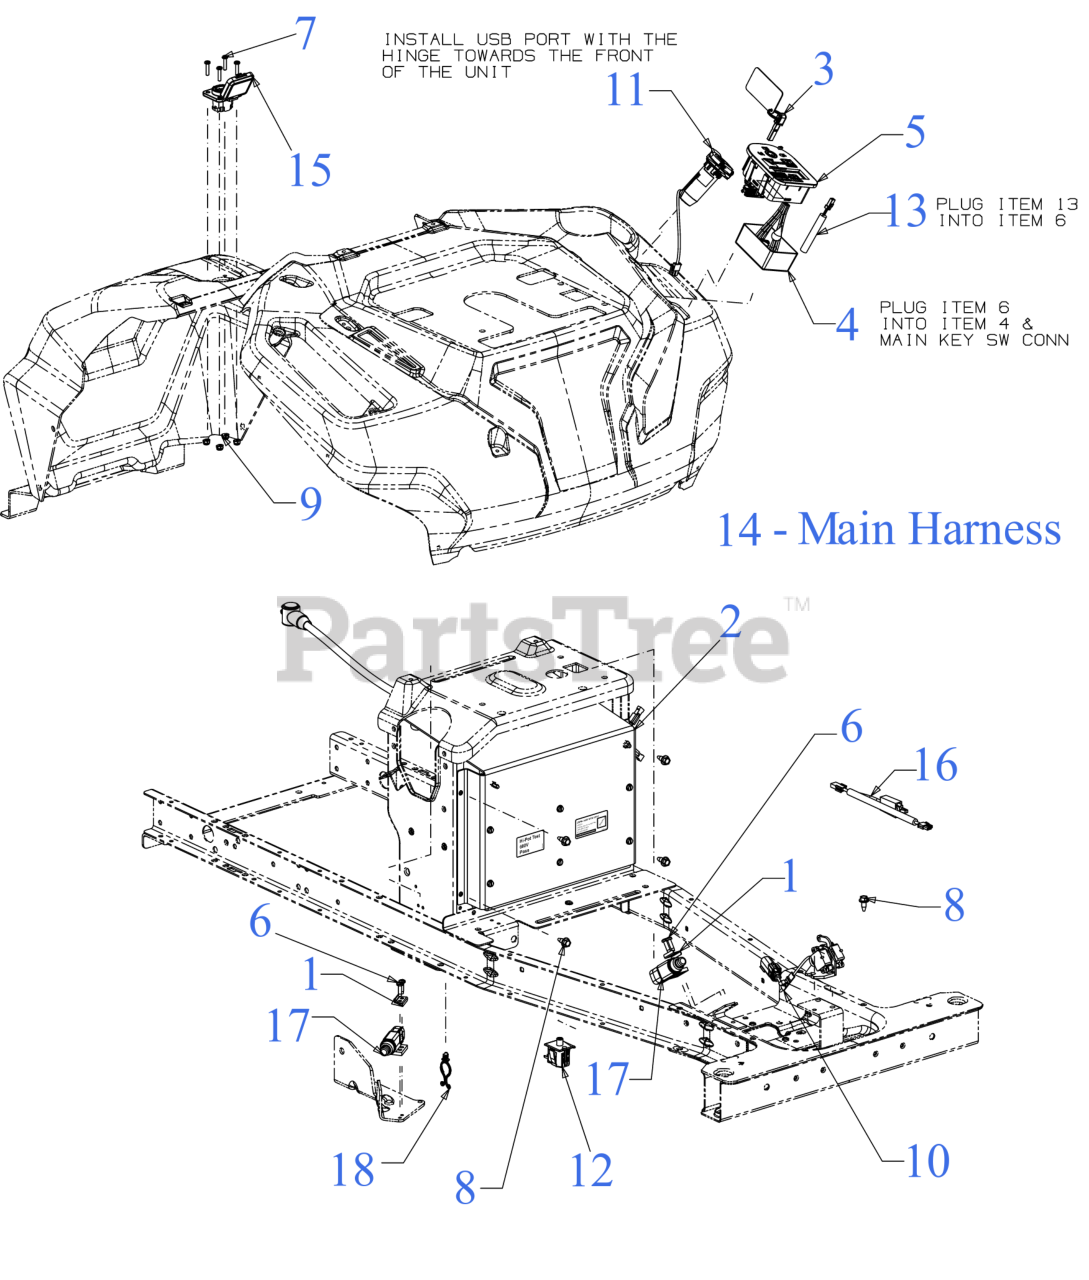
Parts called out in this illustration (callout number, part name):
1	PLATE-SWITCH
2	MOTOR CONTROL PANEL
3	MAGNETIC KEY
4	ELECTRIC MODULE
5	VCM SWITCH ASSEMBLY
7	SCREW #8-32 x .750
8	SCREW 1/4-20X.625
9	HEX NUT #8-32
10	THROTTLE SENSOR (DUEL CLIP)
11	USB RECEPTACLE (12V W/JUMPER)
12	SEAT SWITCH (NC/NO)
14	HARNESS (VCM/SPDM/GEN 1)
15	CHARGER PORT HARNESS (8-PIN)
16	HARNESS (2-PIN HDLT FUSE 1A)
17	SEALED PLUNGER SWITCH
18	TWIST LOCK CLIP
